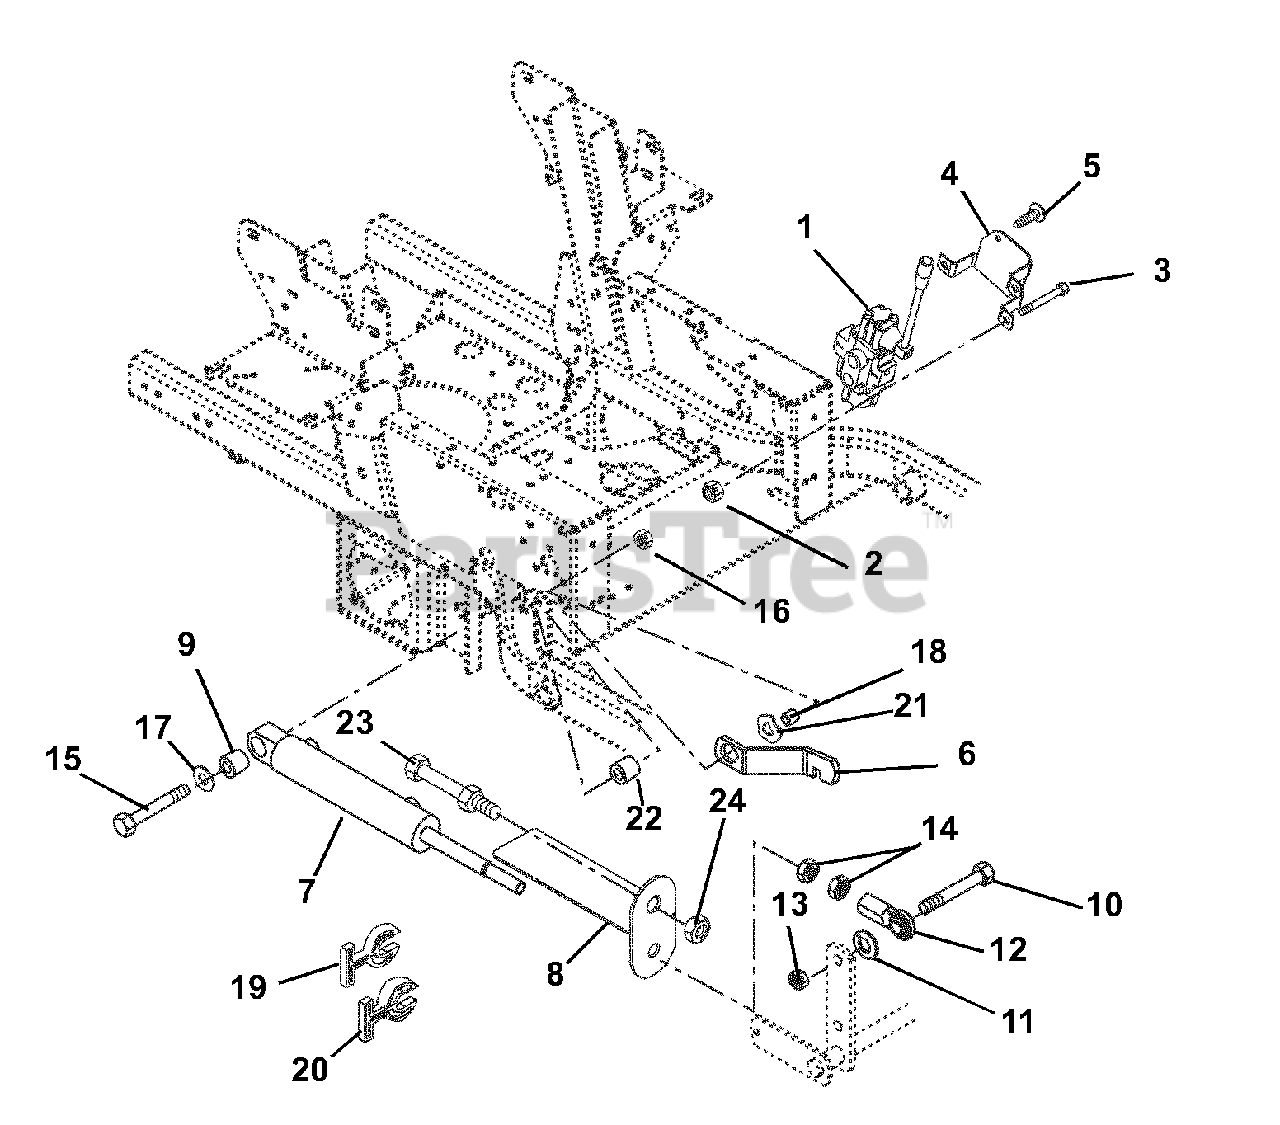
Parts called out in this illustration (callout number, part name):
1	Valve, Hydraulic
2	Nut, Locking Top Flange .31-18
3	Bolt, Hex .31-18 x 2.50 Grade 5
4	Valve Mounting Bracket
5	Screw, Tapping .38-16 x .50 Hex Washer Head
7	Cylinder, Hydraulic Lift
8	Strap, Cut Indicator/Guard
9	Bushing .516 x 1.000 x 1.050
10	Bolt, Hex .62-11 x 2.25 Grade 8
11	Washer, Lock .62 x .156
12	Rod End - Female - Right Hand .63
13	Nut, Locking Center .62-11
14	Nut, Jam .625-18
15	Bolt, Hex .50-13 x 3.50 Grade 5
16	Nut, Locking Top Flange .50-13
17	Washer, Flat Steel .515 x 1.625 x .25
18	Bushing, Flange .515 x .75 x .275 x 1.12
19	Stop, Cylinder .34 Thick
20	Stop, Cylinder .68 Thick
21	Washer, Wave .076 x 1.12 xz .08
22	Spacer .50 I.D. x .88 O.D. x .88
24	Nut-Jam .75-16
